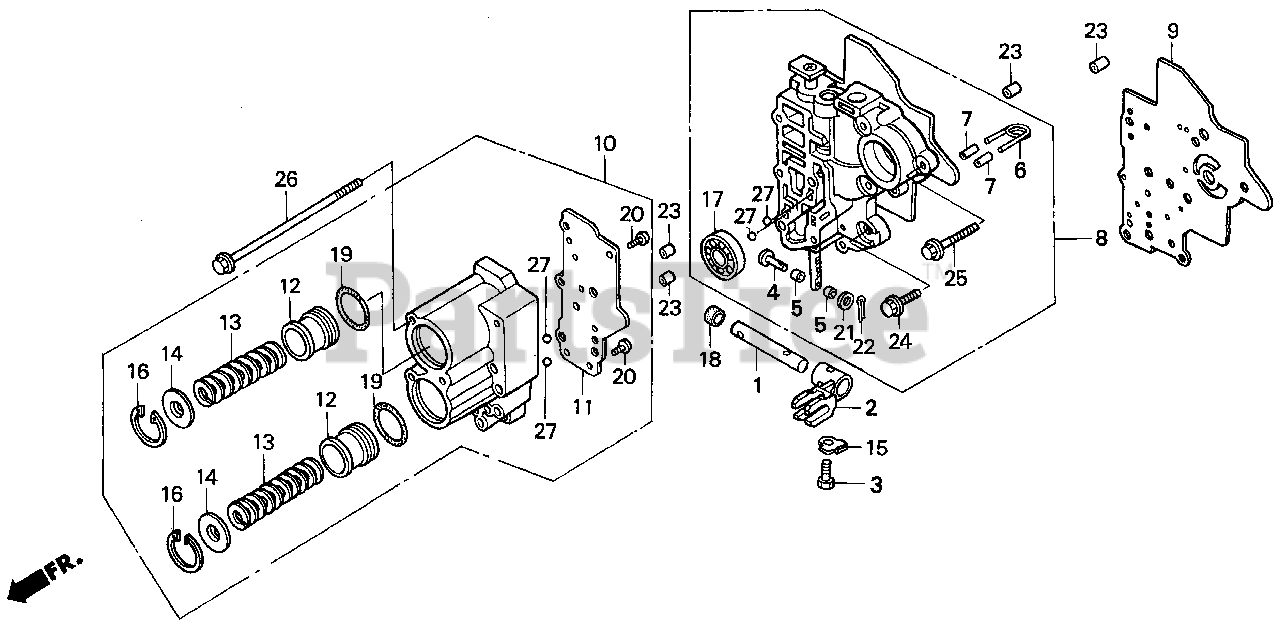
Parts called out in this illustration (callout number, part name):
1	SHAFT, CONTROL
2	LEVER, MANUAL VALVE
3	BOLT, FORK SHAFT SETTING
4	PIN, MANUAL VALVE
5	ROLLER, MANUAL VALVE (NOT AVAILABLE)
6	SPRING, ROLLER
7	ROLLER (6X16) (NOT AVAILABLE)
8	BODY ASSY., MAIN VALVE
9	GASKET, MAIN SEPARATOR
10	BODY ASSY., ACCUMULATOR
11	PLATE, ACCUMULATOR SEPARETOR
12	PISTON, LOW ACCUMULATOR
13	SPRING, ACCUMULATOR
14	COVER, ACCUMULATOR
15	WASHER, LOCK (6MM)
16	CIRCLIP (INNER) (30MM)
17	BEARING, RADIAL BALL (6202)
18	OIL SEAL (12X22X7) (ARAI)
19	O-RING (22.5X2.7)
20	SCREW, PAN (4X8)
21	WASHER, PLAIN (5MM)
22	PIN, COTTER (1.6X12)
23	PIN A, DOWEL (8X14)
24	BOLT, FLANGE (6X18)
25	BOLT, FLANGE (6X35)
26	BOLT, FLANGE (6X105)
27	BALL, STEEL (#7) (7/32)
